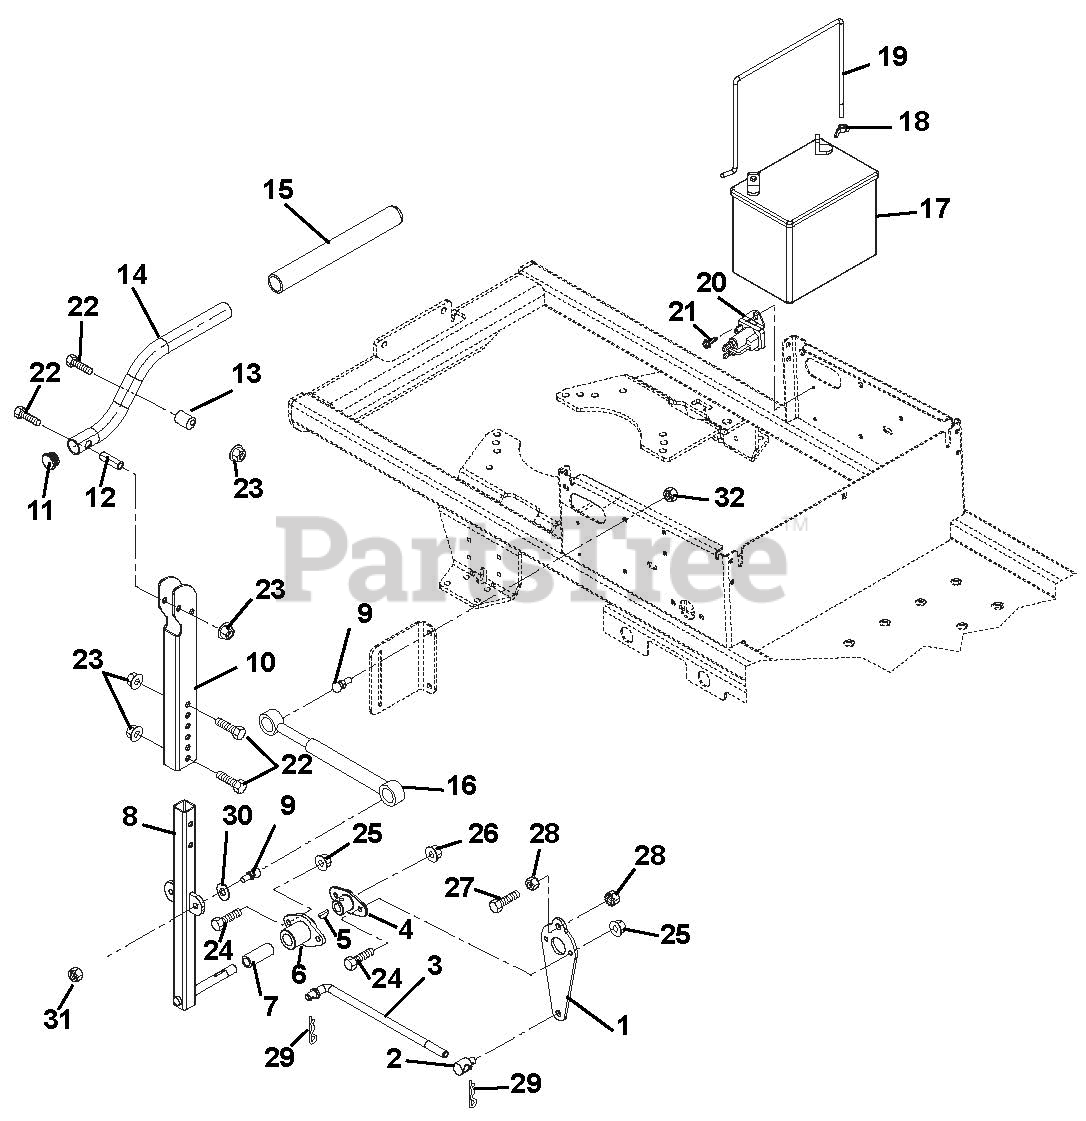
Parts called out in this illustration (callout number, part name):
1	Link, Control
2	Pivot, Rod
3	Link, Wireform
4	Arm, Speed Control
5	Key, Woodruff .125 x .75
6	Bushing, Flanged
7	Bushing, 1/2 x 3/4 x 1-7/8
8	Weldment, Lower Handlebar
9	Stud, Ball
10	Channel, Upper Handlebar
11	Caplug, Handlebar
13	Eccentric
14	Handlebar
15	Grip, Handlebar
16	Damper, Control
18	Nut, Lock Wing .250-20
19	Battery Rod
20	Solenoid
21	Screw, Tap .250-20 x .37
22	Bolt, Hex .31-18 x 1.75 Grade 5
23	Nut, 5/16-18 Flange Nyloc
24	Bolt, Hex .25-20 x .75 Grade 5
25	Nut, Locking Top Flange .25-20
26	Nut, Locking Top Flange .50-13
27	Bolt, Hex .38-16 x 1.75 Grade 5
28	Nut, Spinlock Flange .375-16
29	Pin, Hair #25
30	Washer, Lock .31 x .078
31	Nut, Jam .312-18
32	Nut, Locking Top Flange .31-18
